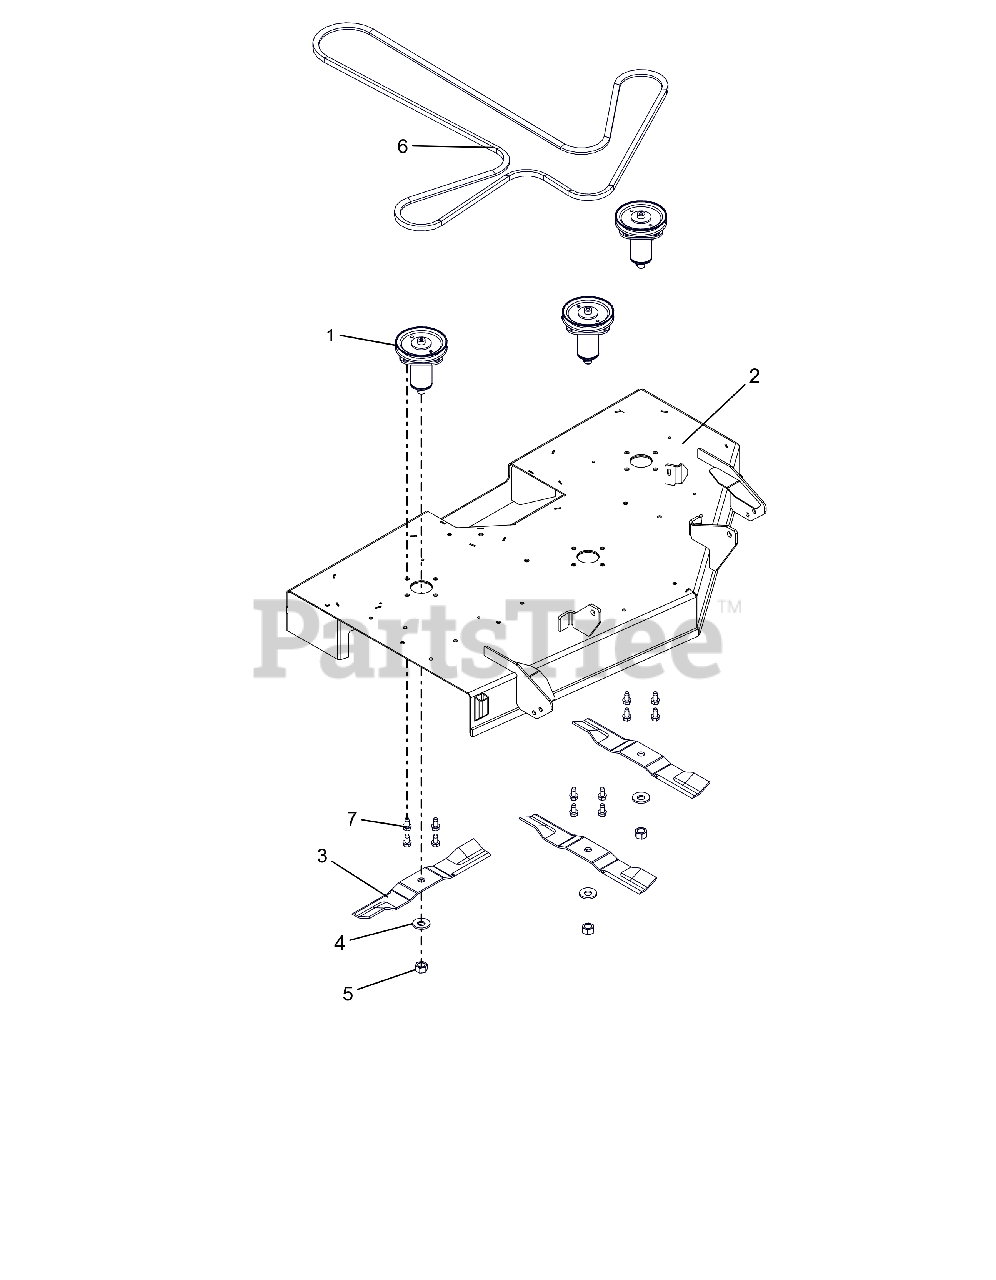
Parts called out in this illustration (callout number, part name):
1	KIT, DECK SPINDLE ASM-IKON-ZTX
2	KIT, 42" ARIENS DECK W/DECALS
3	BLADE, MOWER 15.00"
4	WSHR-BLVL .669X1.535X.138
5	NUT-HEX .62-18 YWZC
6	V-BELT, 4L-WRAPPED
7	@SCR-TAP .38-16X.75 HWH TR YWZ
